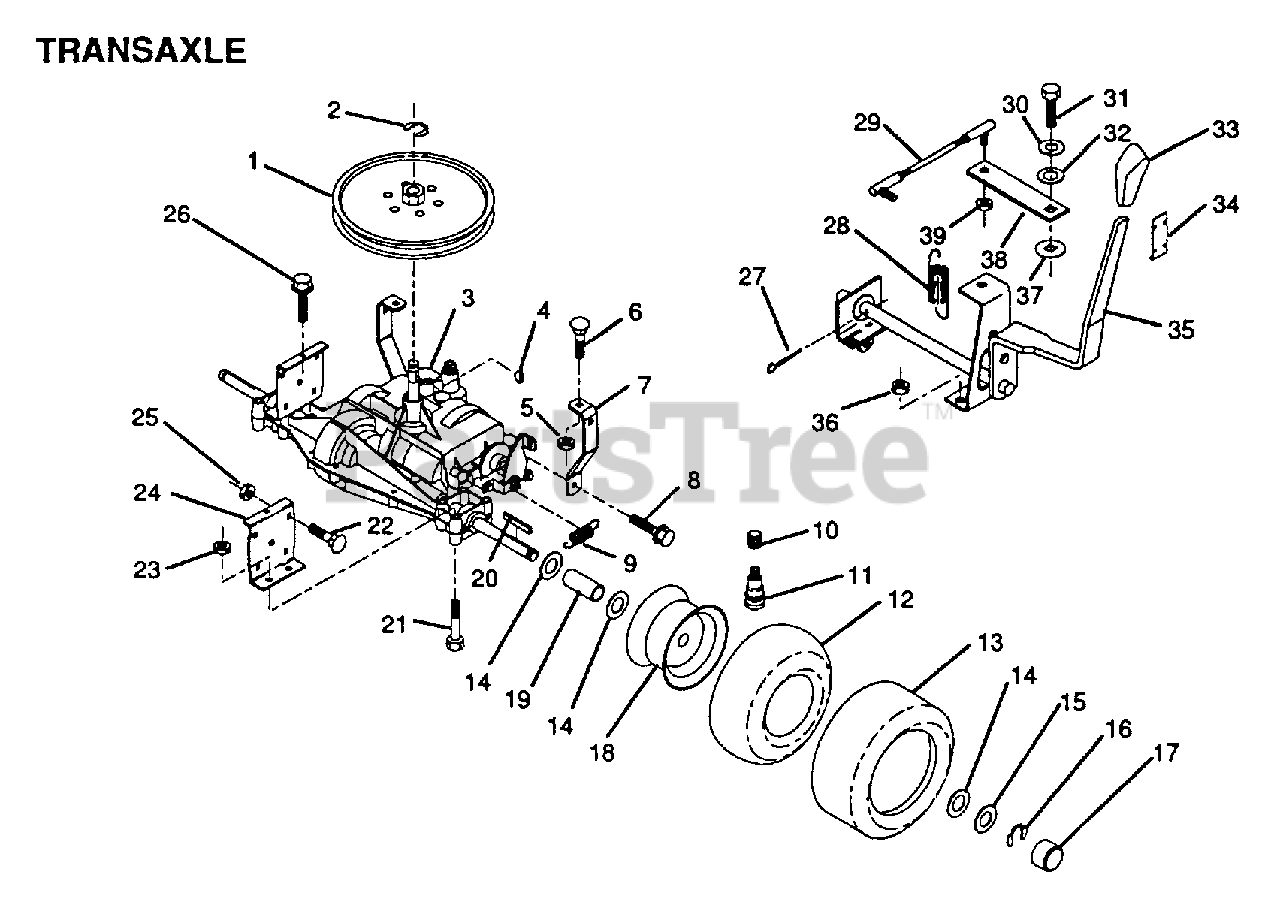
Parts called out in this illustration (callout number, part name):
1	PULLEY
6	BOLT
7	"STRAP,TORQUE"
8	SCREW LT
10	VALVE CAP
11	VALVE STEM LT
12	TUBE.16X6.5/7.5-8
13	TIRE.16X7.5-8
14	WASHER
15	WASHER
16	E-RING LT
17	HUB CAP
19	SPACER
20	SQUARE KEY
21	BOLT
22	BOLT
24	"BRKT,TRANSAXLE"
26	SCREW
27	PIN COTTER 1/8
28	EXT SPRING
29	"LINK,SHIFT"
30	LOCKWASHER
32	WASHER LT
33	"KNOB,SHT CONTROL"
34	KNOB RETAINER
37	WASH-SHFT PLT LT
38	ARM SHIFT
39	NUT.LOCK.5/16-24
